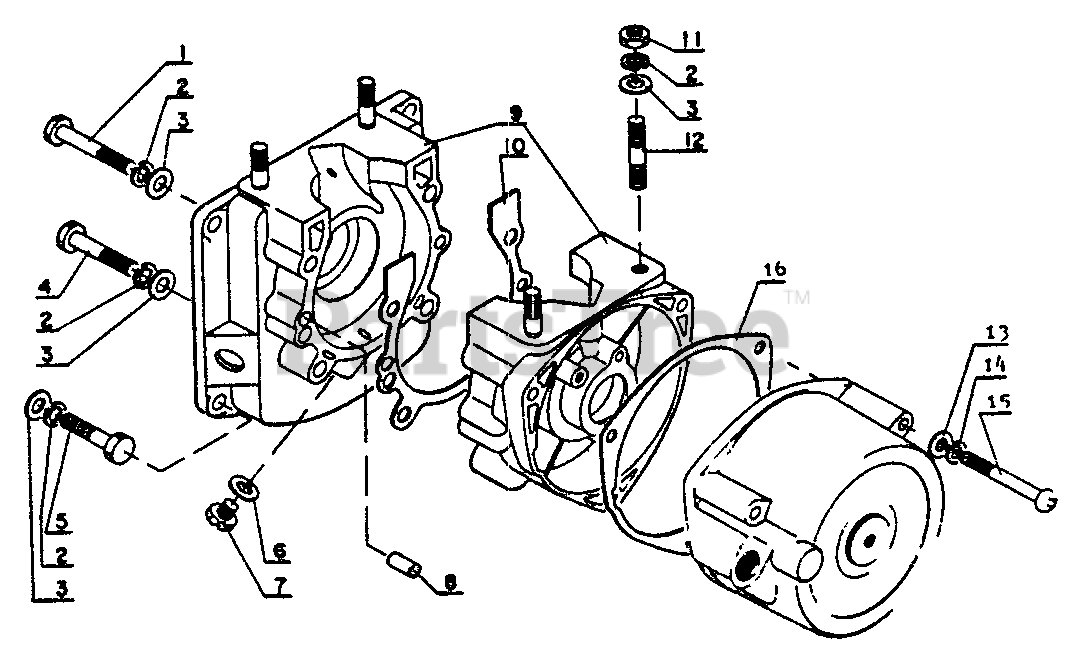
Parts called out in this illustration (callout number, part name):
1	BOLT
2	WASHER, SPRING 6
3	WASHER 6.5×11.5×0.8
4	BOLT
5	BOLT 6×25
7	BOLT, DRAIN
8	PIN, LOCATING 5×10
9	CRANKCASE KIT
10	GASKET, CRANKCASE
11	NUT, HEX M6
13	WASHER, FLAT 5.5×10×0.8
14	WASHER, SPRING 5
15	SCREW 5×42
16	GASKET, STARTER
